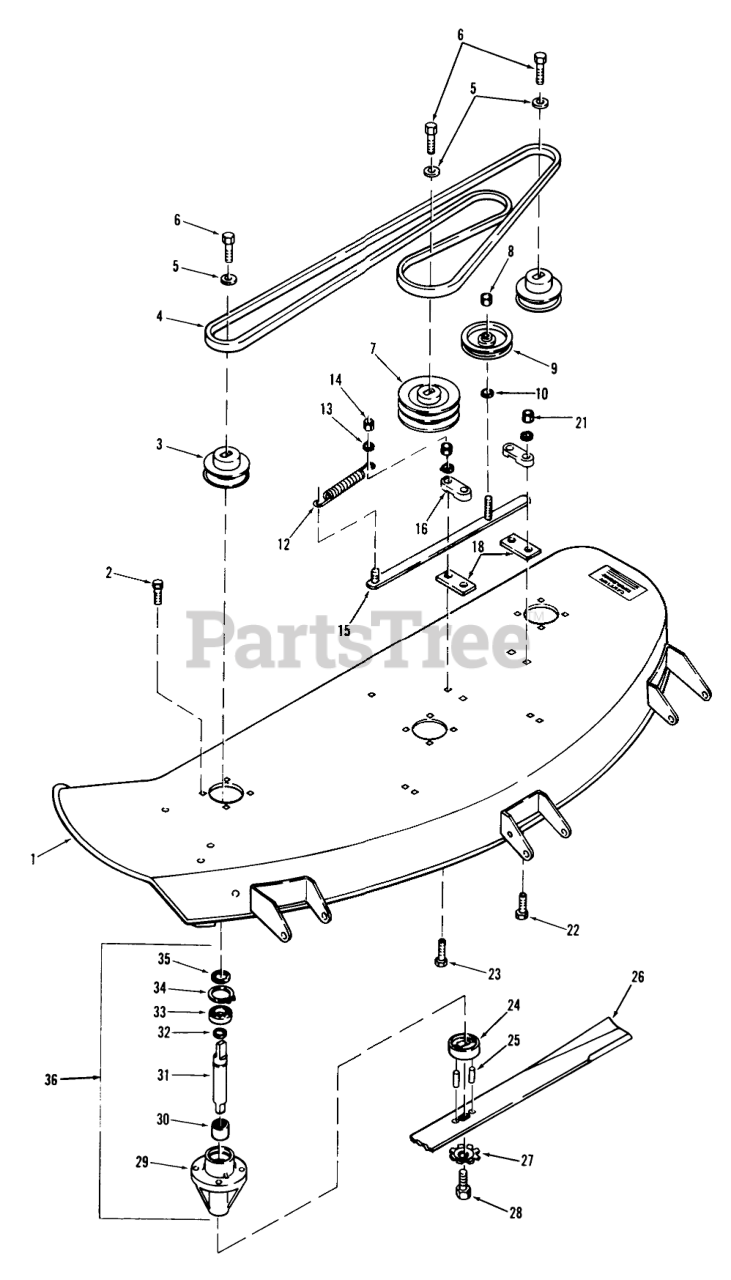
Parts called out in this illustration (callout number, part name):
1	Deck
2	Bolt
3	Pulley-Right & Left
4	V-BELT
5	WASHER
6	Bolt
7	Pulley-Center
8	Nut
9	Pulley-Idler
10	Washer
12	SPRING R
13	WASHER 5/16 SAE
14	Nut
15	ASSY BAR IDLER SUPPO
16	Side Block
18	SLIDE
21	Nut
22	Bolt-Carriage
23	Bolt-Carriage
24	Cup-Spindle
25	SPIROL ROLL PIN
26	BLADE KIT 48 LF
27	WASHER
28	Bolt
29	HOUSING SPINDLE
30	NEEDLE BEARING
31	SHAFT SPINDLE
32	Snap Ring
33	BEARING
34	INT SNAP RING
35	BUSHING
36	Spindle Assy.
